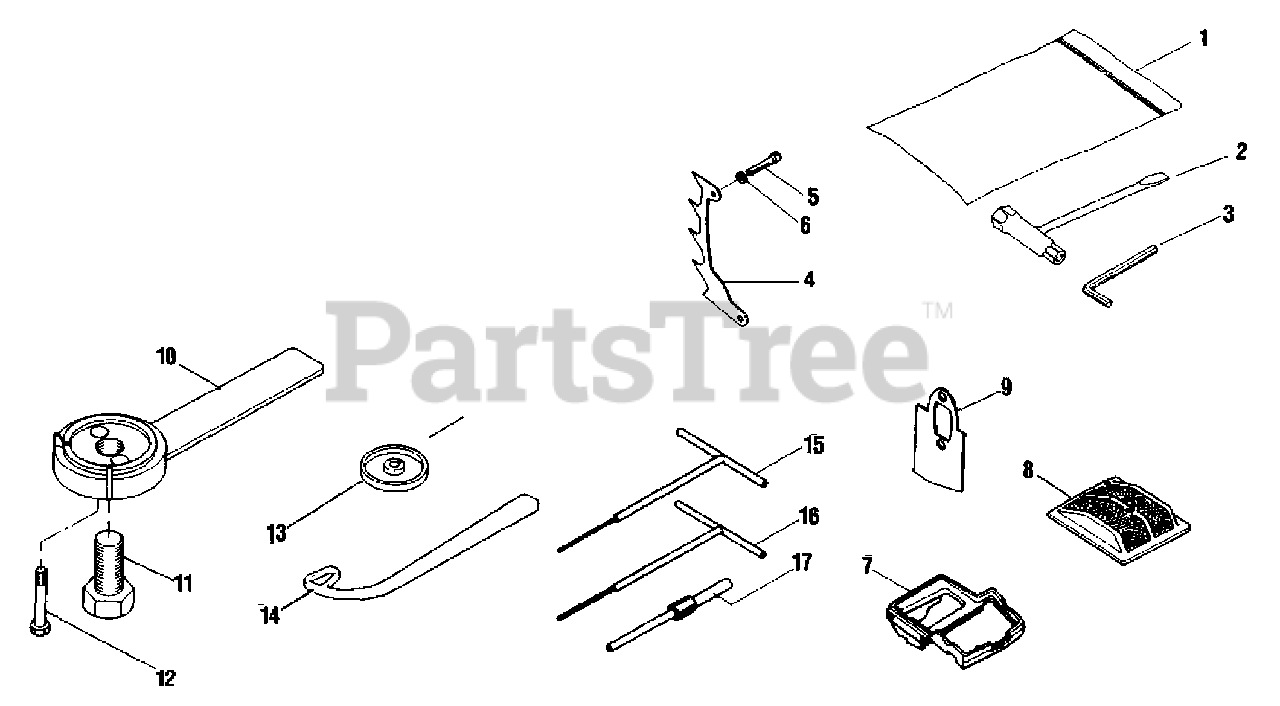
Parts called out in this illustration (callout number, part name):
1	BAG, TOOL
2	T-WRENCH
3	HEX KEY - 4mm
5	SCREW - 5X12
6	LOCKWASHER - 5
7	DUCT, AIR
8	FILTER, AIR - STAINLESS
9	GASKET, EXHAUST
11	BOLT, CENTER
13	SET GAUGE
14	FLYWHEEL WRENCH
15	T-WRENCH - 4mm
16	T-WRENCH - 5mm
17	PIN, SET
